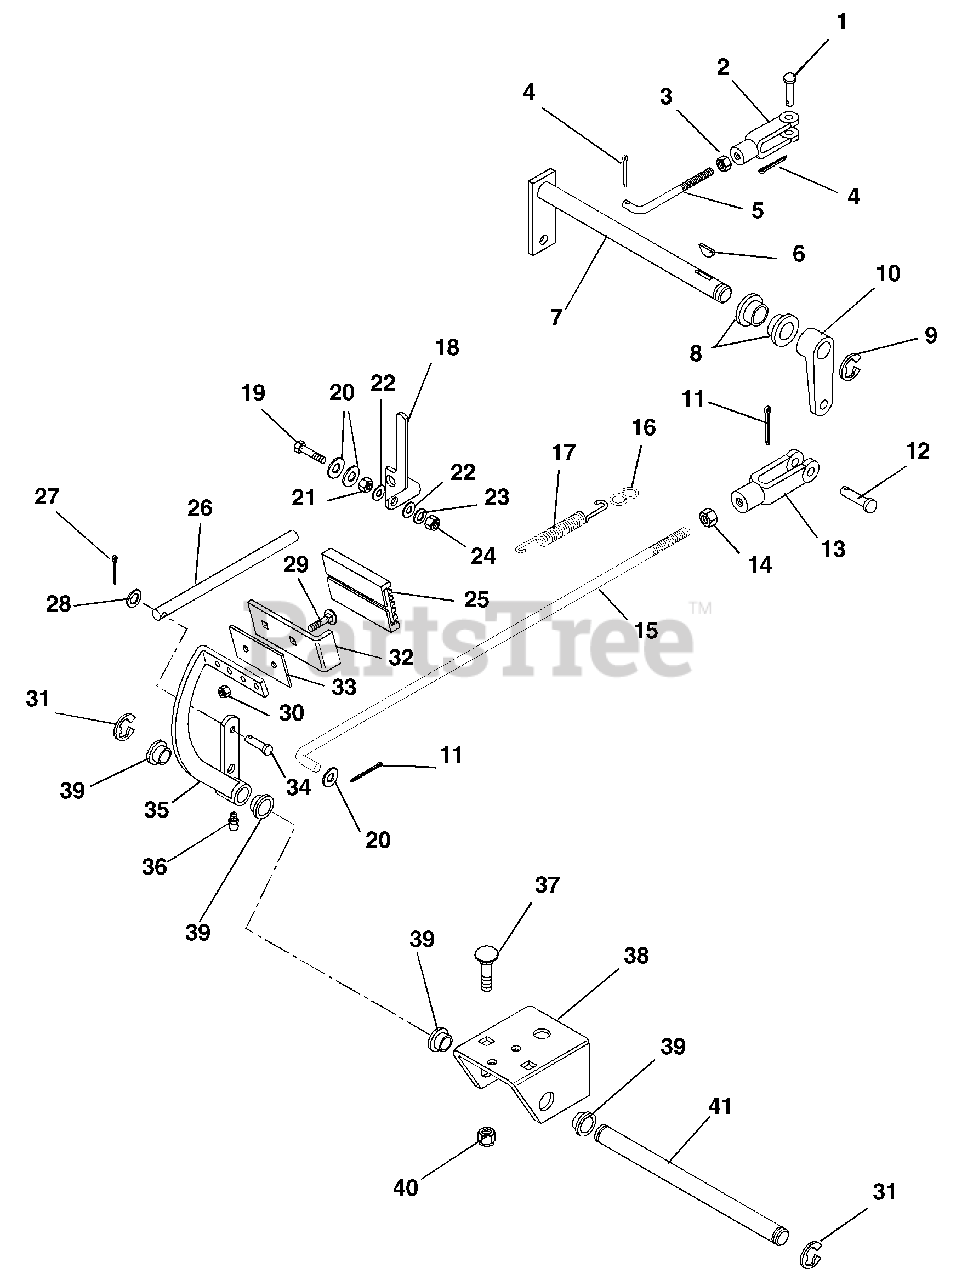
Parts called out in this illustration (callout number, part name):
1	Pin-Clevis .31 x .94
2	Yoke, .31-24 x 2.25
3	Nut- Jam .31-24
4	Pin-Cotter .09 x .75
5	Rod, Parking Brake
6	Key-Woodruff .19 x .75
7	Weldment, Brake Cross Shaft
8	Bushing-Flange .76 x 1.00 x .58 x 1.48
9	Ring-Retaining-External .57 x .05
10	Lever, PTO
11	Pin-Cotter .12 x .75
12	Pin-Clevis .38 x .95
13	Clevis,.38-24 Adjustable
14	Nut-Jam .38-24
15	Rod,Brake Right Hand
16	Clip, Spring
17	Spring-Tension .095 x .50 x 5.5
18	Arm, Parking Brake Lock
19	Bolt-Hex .38-16 x 1.25 Grade 5
20	Washer-Flat-Steel .41 x .81 x .065
21	Nut-Hex-Jam .38-16
22	Washer-Flat-Nylon .38 x .75 x .060
23	Washer-Locking .38 x .094
24	Nut-Locking-Center .38-16
25	Pad, Pedal
26	Rod
27	Pin-Cotter .06 x .75
28	Washer-Flat-Steel .28 x .62 x .065
29	Bolt-Round Head Square Neck .25-20 x 1.25 Grade 5
30	Nut-Locking-Center .25-20
31	Ring-Retaining-External .63 x .042
32	Pedal, Brake
33	Plate, Brake
34	Pin-Clevis .25 x 1.13
35	Weldment, Brake Pedal
36	Fitting, Lube .25-28 x .26
37	Bolt-Round Head Square Neck .38-16 x .75 Grade 2
38	Bracket, Brake Pedal
39	Bushing-Flange .63 x 1.00 x .63 Nylon
40	Nut-Locking-Center .38-16
41	Shaft, Brake Pedal Mounting
